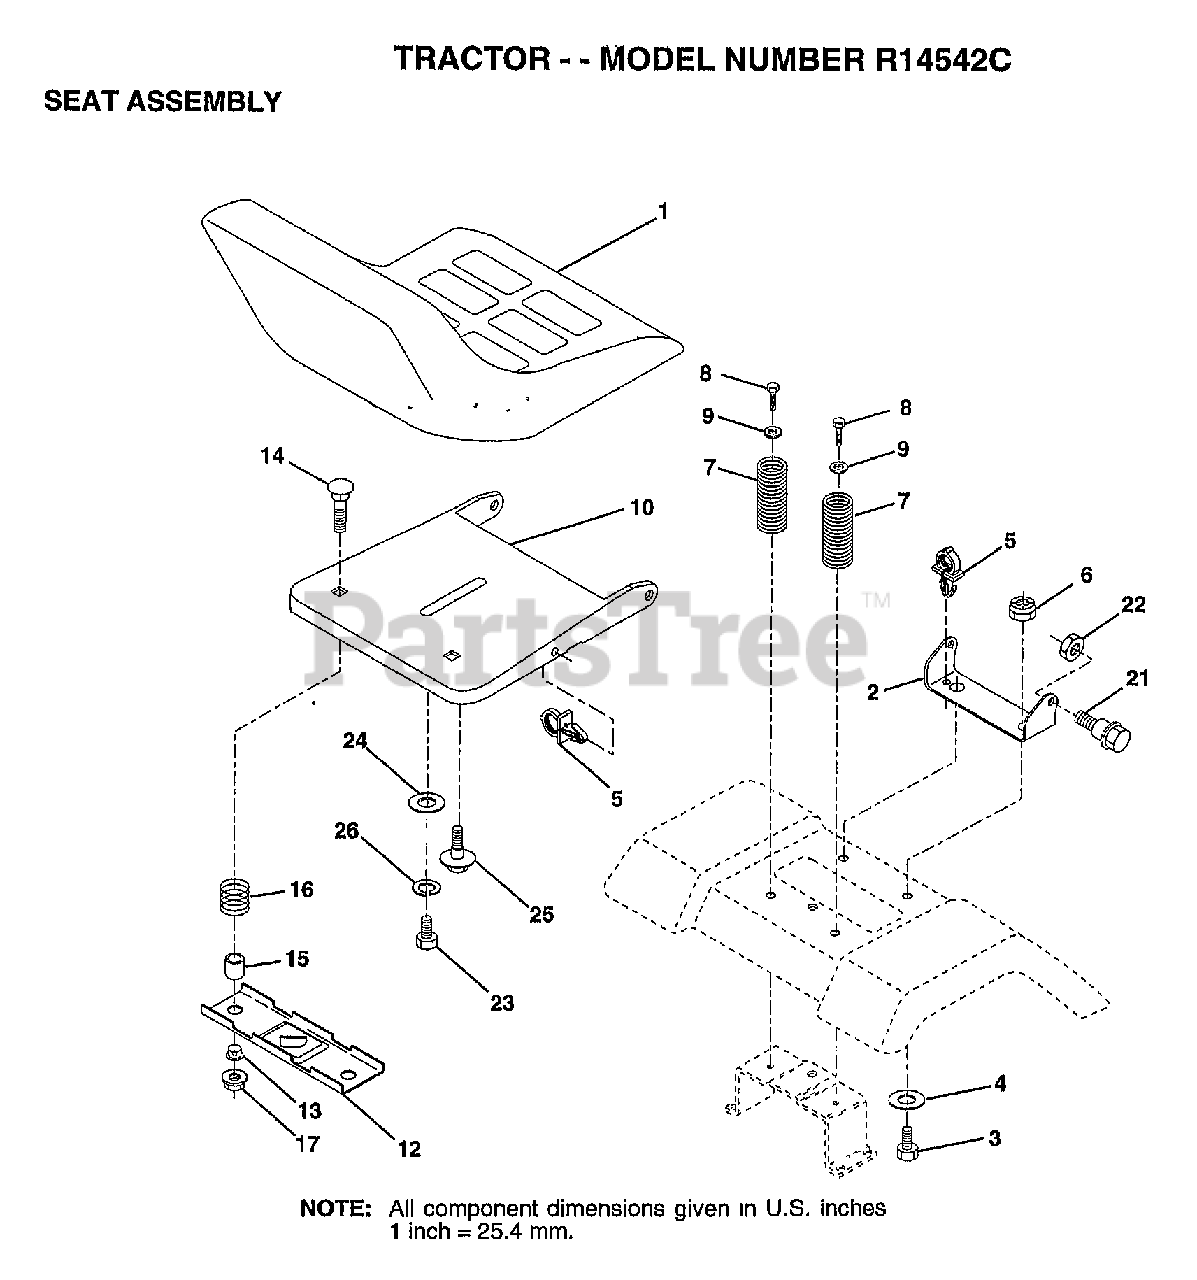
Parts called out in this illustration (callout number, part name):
2	BRACKET PVT SEAT
3	BOLT
4	WASHER PM
5	CLIP.PUSH-IN.HING
6	NUT
7	SPRING COMPRESSIO
8	SCREW GTV
9	WASHER
10	PAN-SEAT
12	BRKT SWITCH
13	BUSHING
14	BOLT-RD HD SQ NK
15	SPLIT SPACER
16	SPRING
21	"BOLT,SHOULDER"
22	NUT
23	BOLT
24	WASHER
25	"BOLT,SHOULDER"
26	LOCKWASHER
